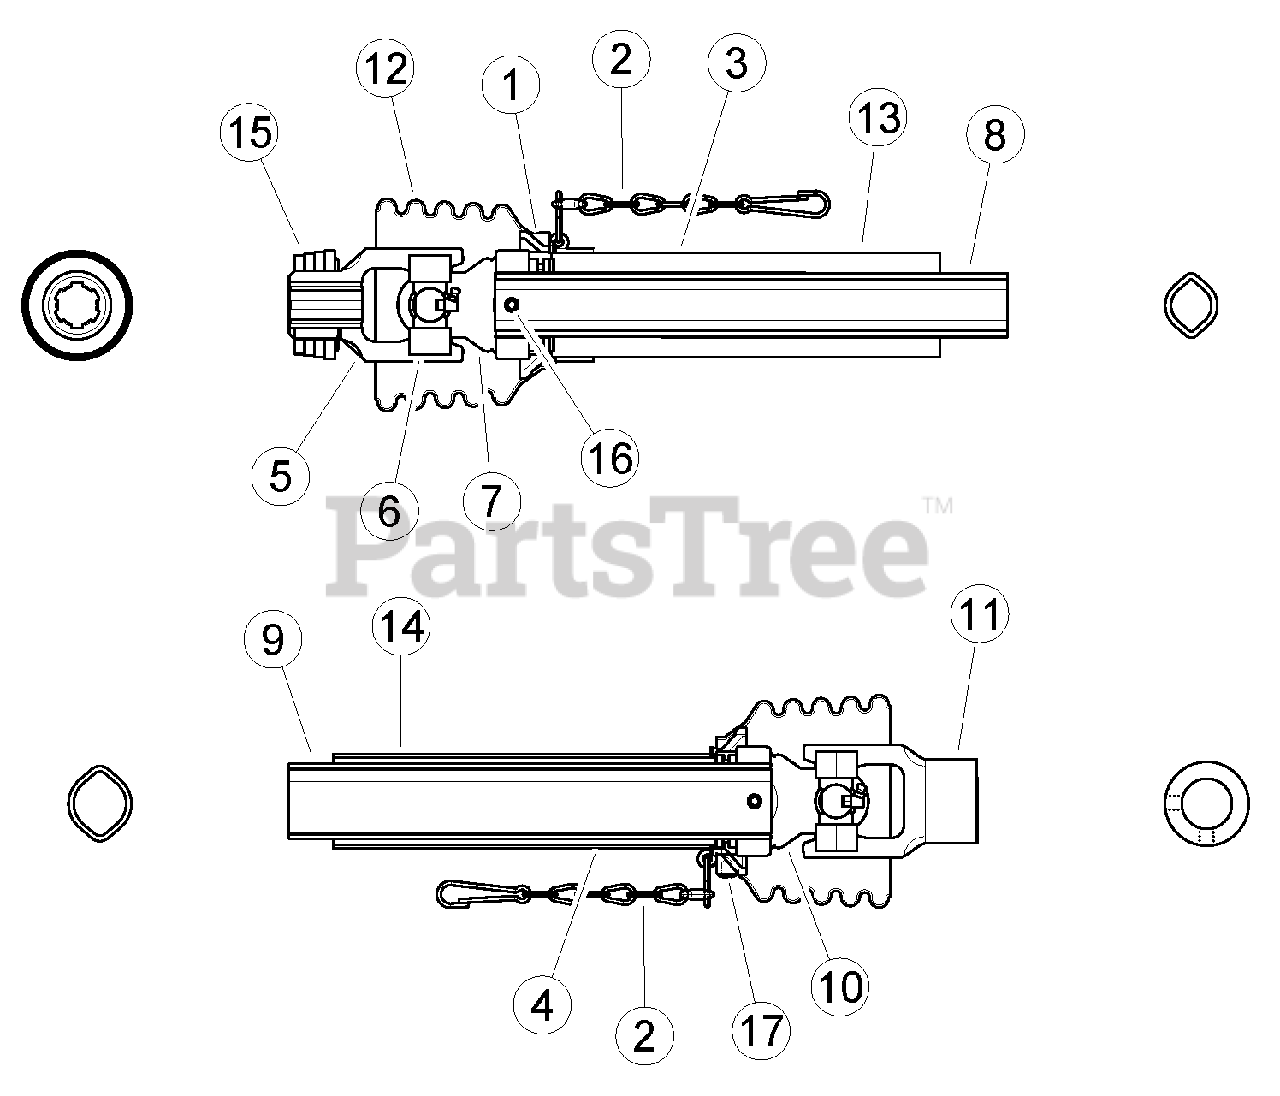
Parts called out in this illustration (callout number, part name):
1	BEARING, RING SC15
2	SAFETY CHAIN
3	DECAL, OUT
4	DECAL, IN
5	YOKE, 3/8 - 6 SPL. ASGE
6	CROSS & BEARING KIT
7	YOKE, INBOARD OV
8	INNER PROFILE OV
9	OUTER PROFILE I
10	YOKE, INBOARD I
12	SHIELD, CONE 4 RIB
13	SHIELD, OUTER TUBE OVL.
14	SHIELD, INNER TUBE RND
15	KIT, RETAINING RING / TRACTOR SIDE
16	PIN, SPRING 10 X 65
